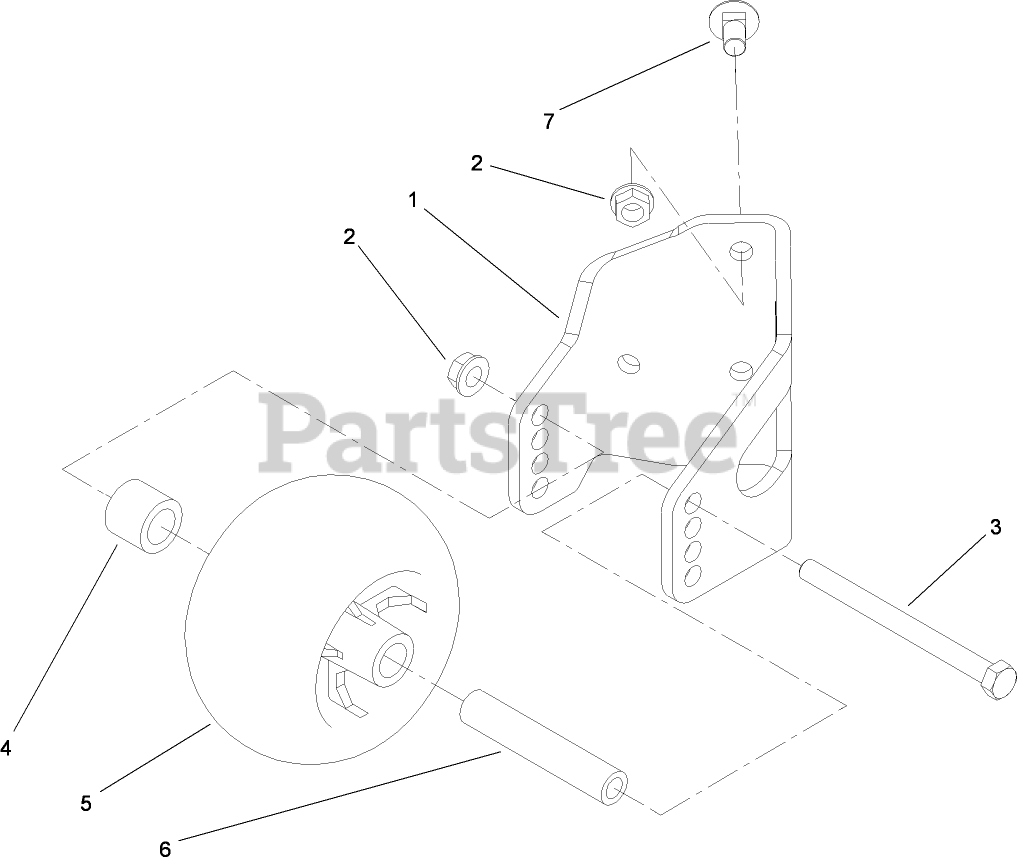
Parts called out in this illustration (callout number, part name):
1	BRACKET-ROLLER, RH
2	NUT-HHF, WHIZ
3	SCREW-HH
4	TUBE-SPACER
5	ROLLER-SCALP, ANTI
6	TUBE-SPANNER
7	SCREW-CARR
